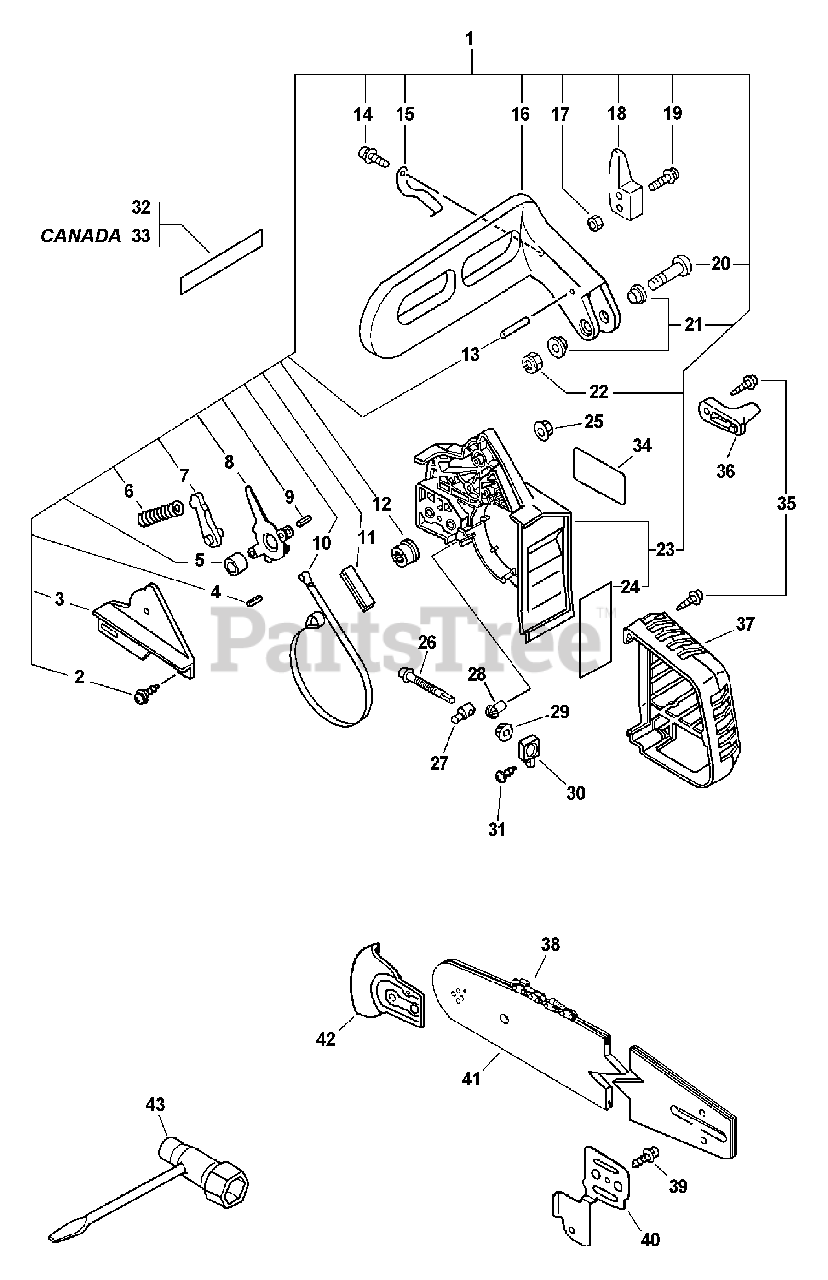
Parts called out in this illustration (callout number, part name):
1	CHAIN BRAKE ASSY
2	SCREW - 4X12 -- TAPPING
3	COVER, BRAKE - GRAY
4	PIN - SPRING -- 2.5X12
5	SPACER - 8
6	SPRING, BRAKE
7	STOPPER, BRAKE
8	LEVER, BRAKE
9	PIN - SPRING -- 4X8
10	BAND, BRAKE
12	ADJUSTER, BRAKE BAND
13	ROLLER - 4X23.8
14	SCREW - 4X12 -- TAPPING
15	SPRING, RETURN
16	LEVER, BRAKE - ORANGE
18	WEIGHT, BRAKE
19	SCREW - 4X22
20	SCREW - 5X32
22	LOCKNUT - 5
23	GUARD, SPROCKET - GRAY
24	DEFLECTOR, HEAT
25	NUT - 6 -- FLANGE
26	SCREW, TENSIONER
27	TENSIONER, CHAIN
28	GEAR - PINION
29	GEAR - BEVEL
30	BRACKET, TENSIONER
31	SCREW - 4X12 -- TAPPING
32	LABEL - BAR & CHAIN
33	LABEL - BAR & CHAIN
34	LABEL - MODEL CS-301
35	SCREW - 5X20 -- TAPPING
36	CATCHER, CHAIN
37	COVER, EXHAUST
38	SAW CHAIN - 12" (30cm)
38	SAW CHAIN - 14" (35cm)
38	SAW CHAIN - 16" (40cm)
39	SCREW - 4X10
40	PLATE, GUIDE - OUTER
41	GUIDE BAR - 12" (30cm)
41	GUIDE BAR - 14" (35cm)
41	GUIDE BAR - 16" (40cm)
42	KICK GUARD KIT
43	T-WRENCH - 10X19mm
